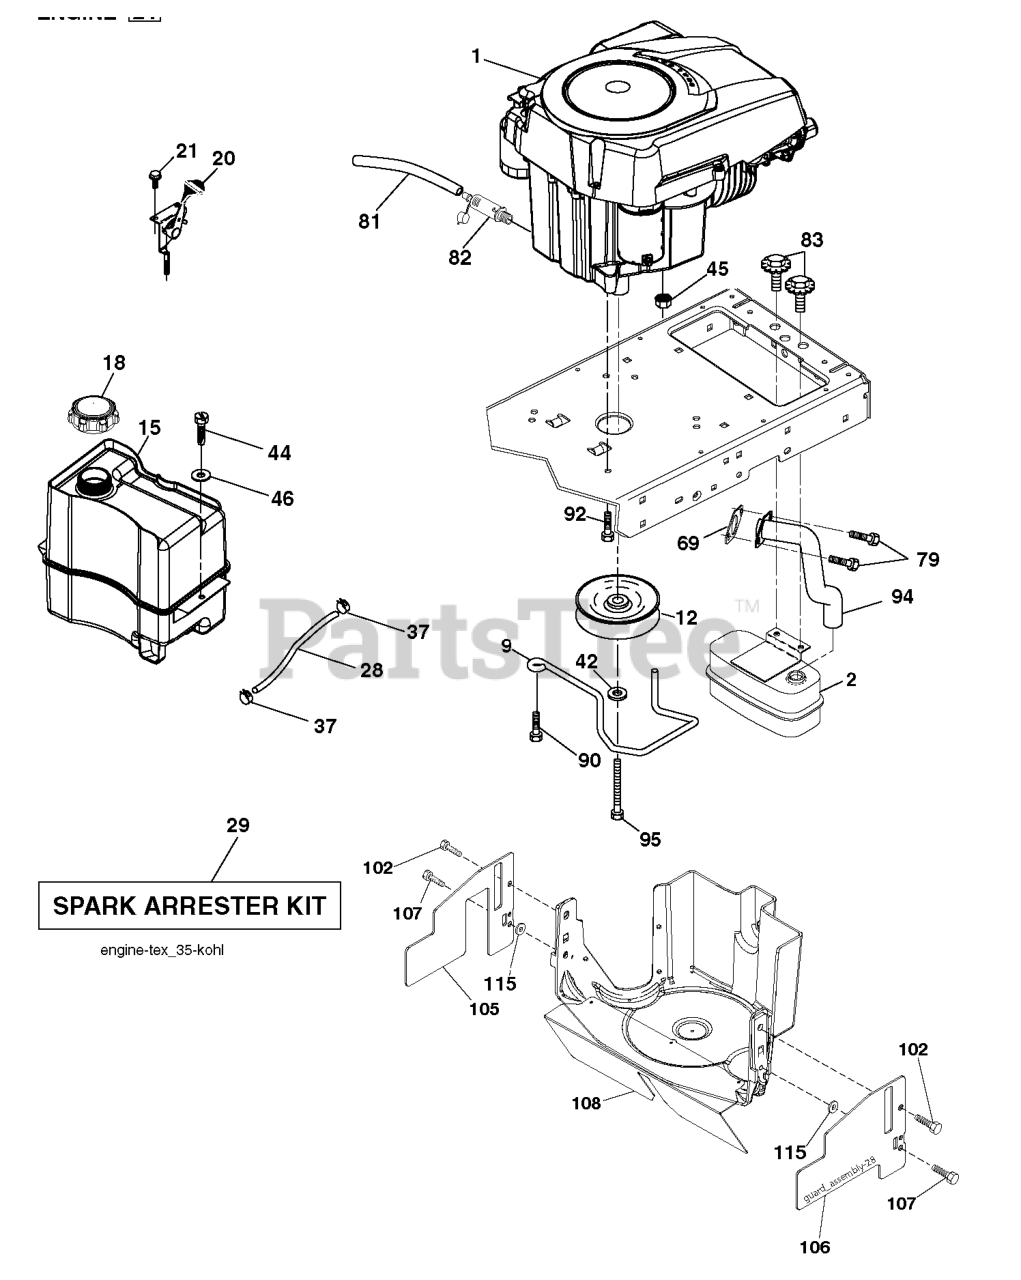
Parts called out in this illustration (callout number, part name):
2	MUFFLER.SINGLE.CYL.KOHL/B&S
9	KEEPER.BELT.ENGINE.3.25 (3 2)
12	PULLEY ENGINE
15	RP TANK FUEL FRT 1.5 GAL
18	FUEL CAP
20	CONTROL.TH/CK.C.
21	SCREW.#10 X 0.750.BOS
28	LINE.FUEL.20
29	KIT.SPARK ARRESTOR 794945 B&S
37	HOSE CLAMP
42	LOCKWASHER
44	SCREW HEXWSHR 1/4-20X3/4
45	NUT
69	GASKET.EXHAUST.KOHLER
79	SCREW.SOCKET HD.5/16-1
81	TUBE, DRAIN OIL ASM.
82	PLUG DRAIN OIL EASY
83	BOLT.5/16-18UNCX3/4 W/SEMS.BLK
90	SCREW 3/8-16X1
92	SCREW 3/8-16X1
94	RP.TUBE.EXHAUST.KOHL.COURAGE
95	BOLT HEX 7/16-20X4-1/4"
102	SCREW
105	SHIELD.SIDE.LH.3842"TEX FRENCH
106	SHIELD.SIDE.RH.3842"TEX FRENCH
107	SCREW.1/4-20X5/8
108	ENGINE COVER
115	PALNUT 1/4
